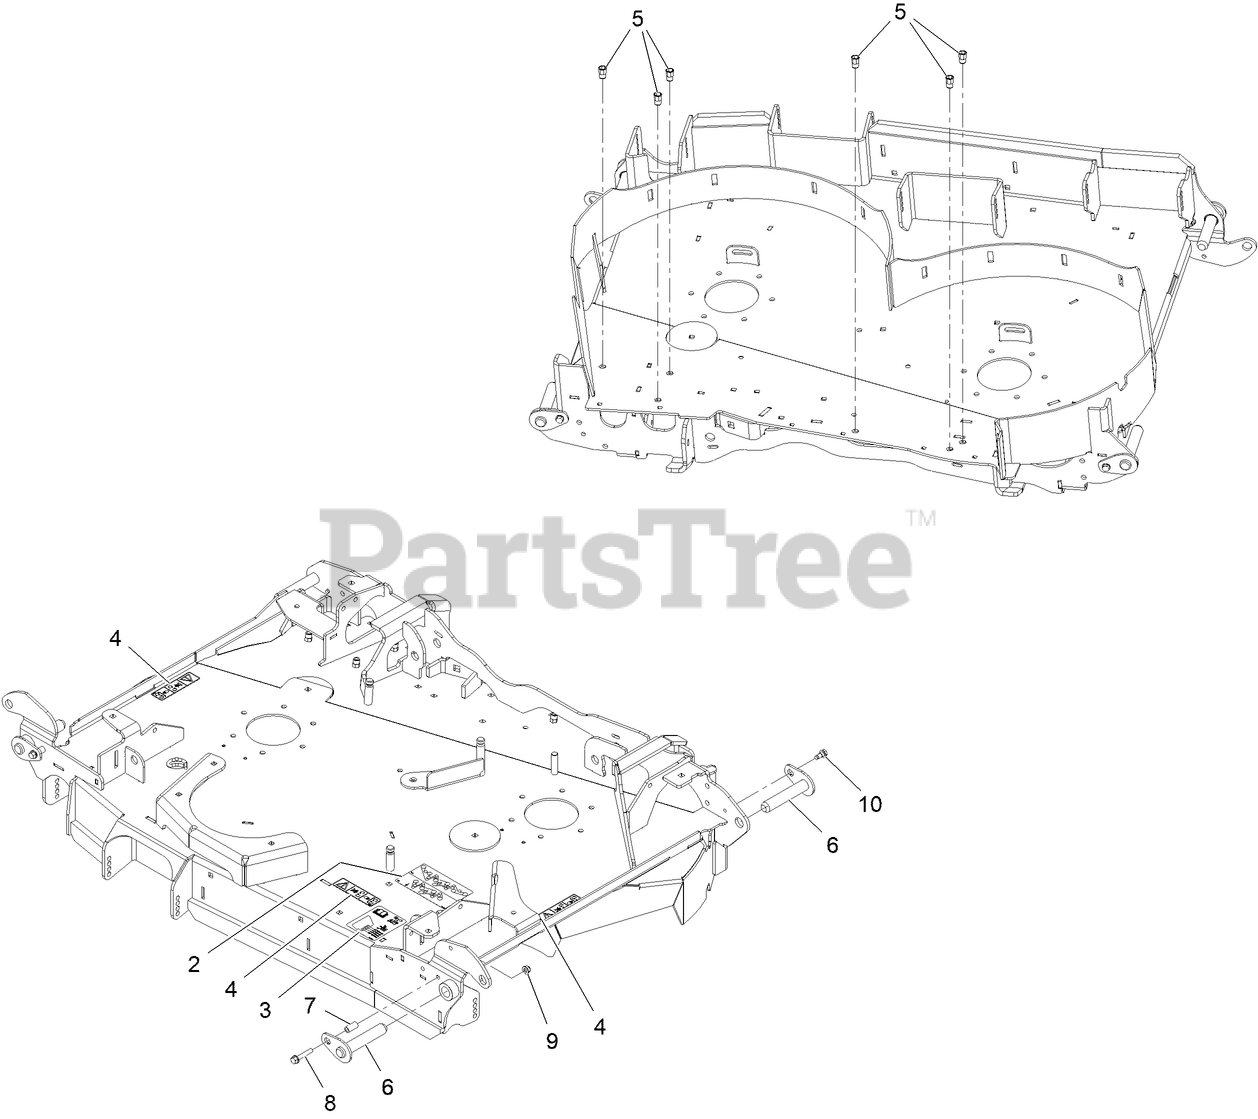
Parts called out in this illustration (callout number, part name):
2	DECAL-DECK BELT ROUTING
3	DECAL-ROLLER, ANTI-SCALP
4	DECAL-COVER, MISSING
5	NUT-CLINCH,HEX
6	ASM-DECK PIN
7	Tube-Standoff
8	Screw-HWH
9	NUT-HF, NI
10	SCREW-SHOULDER
